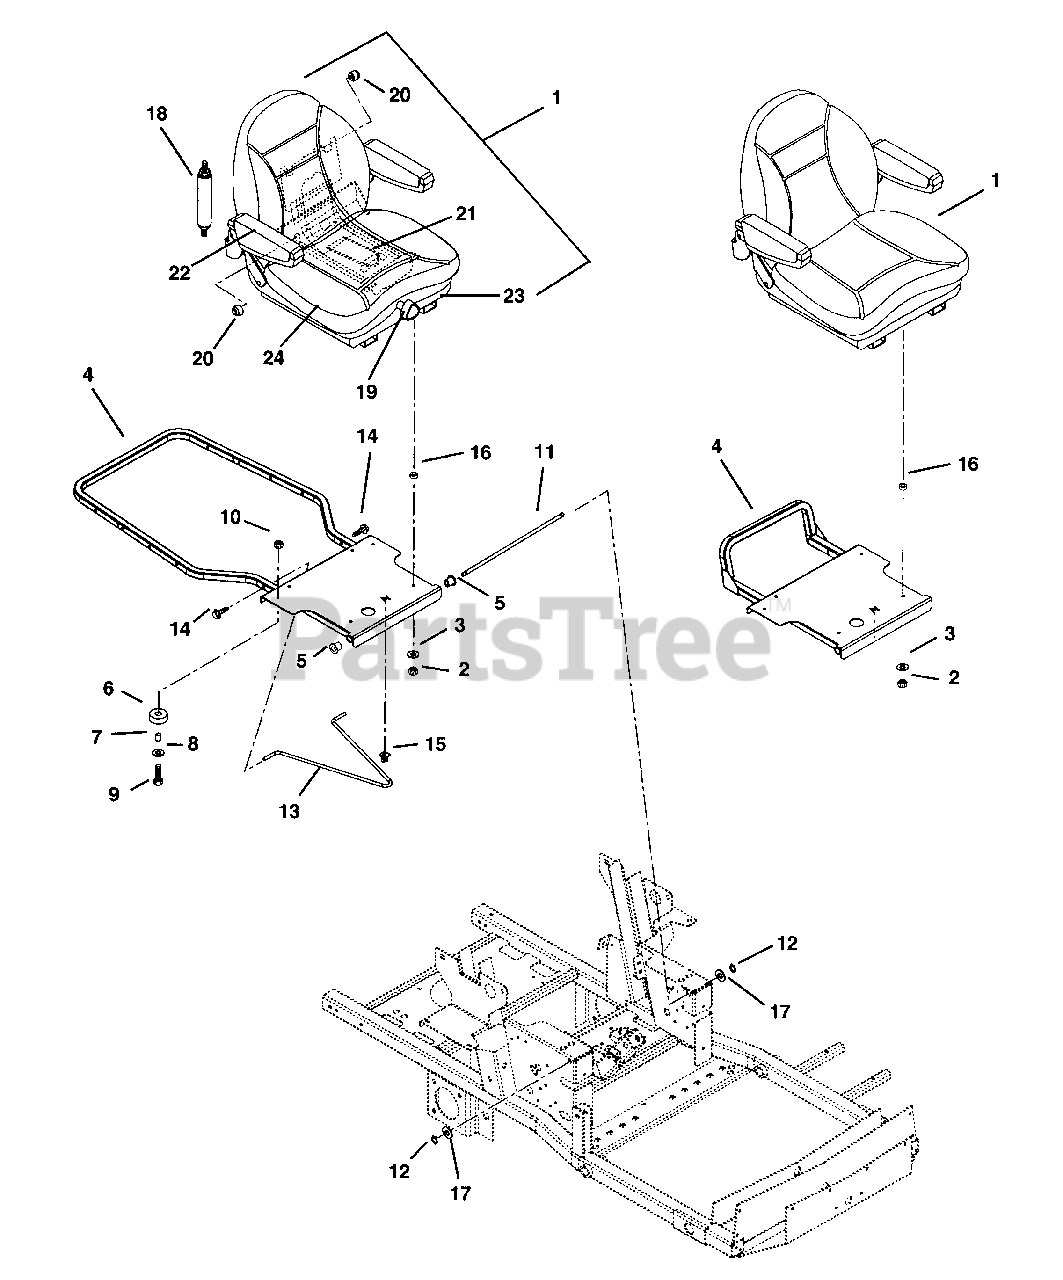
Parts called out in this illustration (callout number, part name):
1	Seat, Suspension
1	Seat, MILSCO Suspension
1	Nut-Locking-Center M8-1.25
3	Washer-Flat-Steel .38 x .875 x .083
4	Weldment- Hood Frame
4	Weldment - Seat Frame
5	Bushing-Flange .515 x .750 x .745 x 1.00
6	Bumper-Seat
7	Bushing-Sleeve .265 x .375 x .250
8	Washer-Flat-Steel .312 x .734 x .065
9	Bolt-Hex .25-20 x .75 Grade 5
10	Nut-Locking-Center .25-20
11	Rod-Seat Frame Pivot
12	Ring-Retaining-External .500 x .050
13	Rod-Prop
14	Screw-Tapping .25-20 x .50 Hex Washer Head
15	Clip
16	Bushing-Sleeve .377 x .624 x .235
17	Washer-Flat-Steel .531 x 1.06 x .095
18	Kit-Damper w/Hardware
19	Kit-Knob (1 per bag)
20	Kit-Roller (4 per bag)
21	Kit-Spring Cable (1 per bag)
22	Kit-Arm Pad (1 per bag)
23	Kit-Adjuster (1 per carton)
24	Kit-Cushion (1 per carton)
